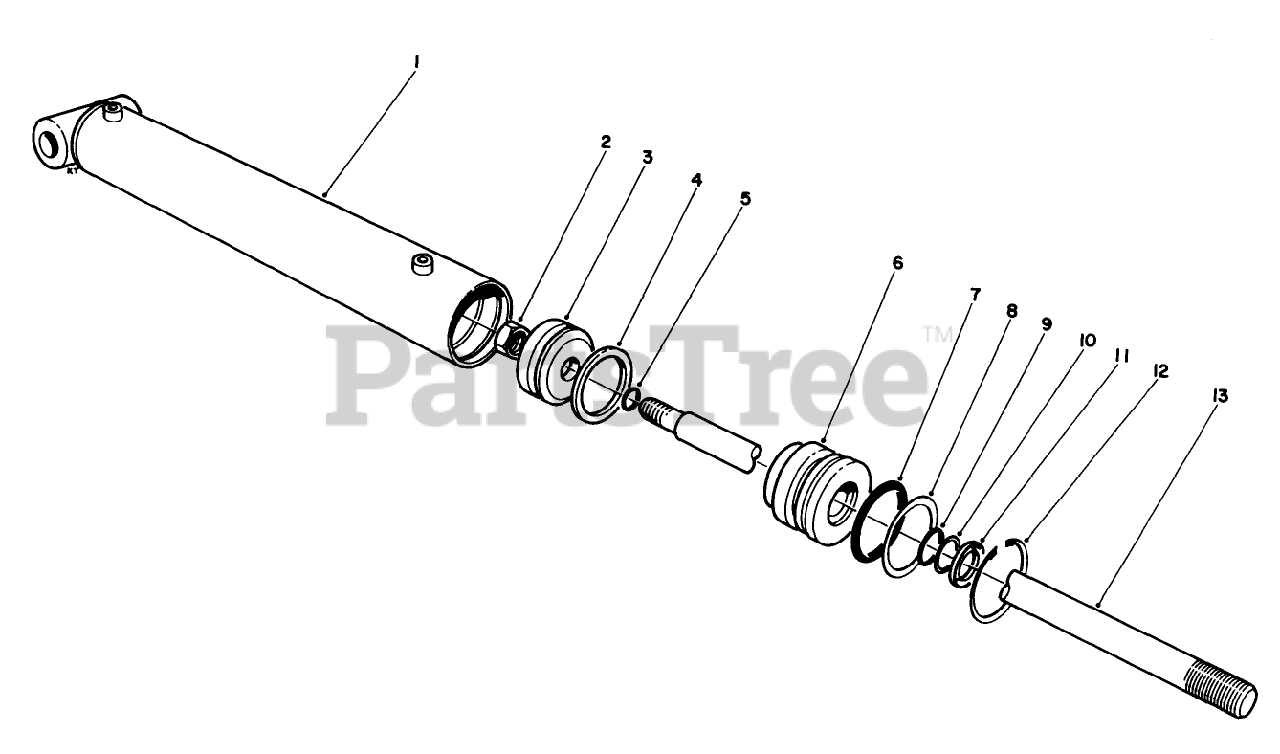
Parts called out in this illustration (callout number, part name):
1	Barrel
2	LOCKNUT
3	PISTON
4	Uniring
5	O-Ring
7	O-Ring
8	Washer-Backup
9	"0" Ring
10	Washer-Backup
11	Dust Seal
12	RING-RETAINING
13	SHAFT
